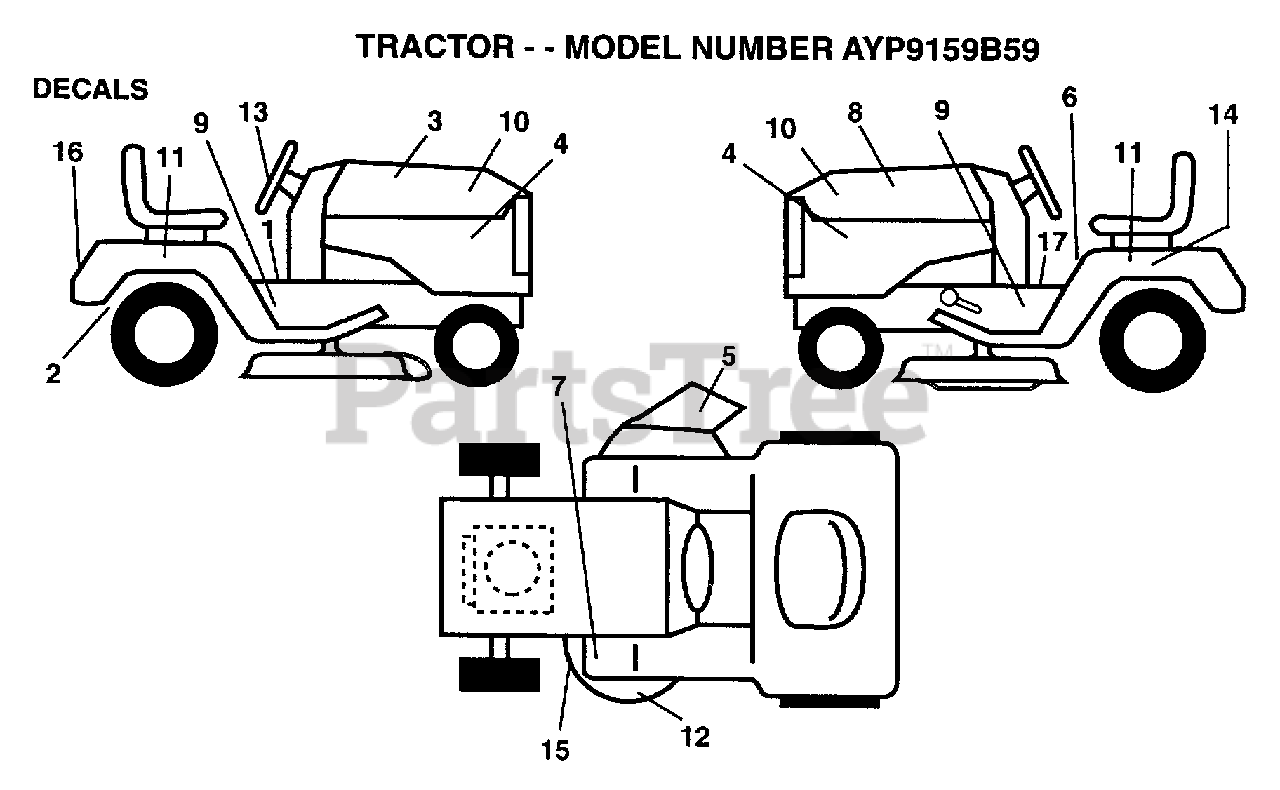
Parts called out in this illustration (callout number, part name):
2	DECAL DRAWBAR LH
3	DECAL HOOD RH
4	DECAL.PNL.SD.VANG
5	DECAL DECK MULCH
6	DECAL
8	DECAL HOOD LH
9	"DECAL.CHASSIS.42"""
10	NAMEPLATE.HD.WIZA
11	DECAL.FENDER.WIZ
12	DECAL DECK WIZ +
13	DECAL STEER WHL
14	DECAL.BATRY.3-3908
15	DECAL
17	DECAL SADLE HYDRO
